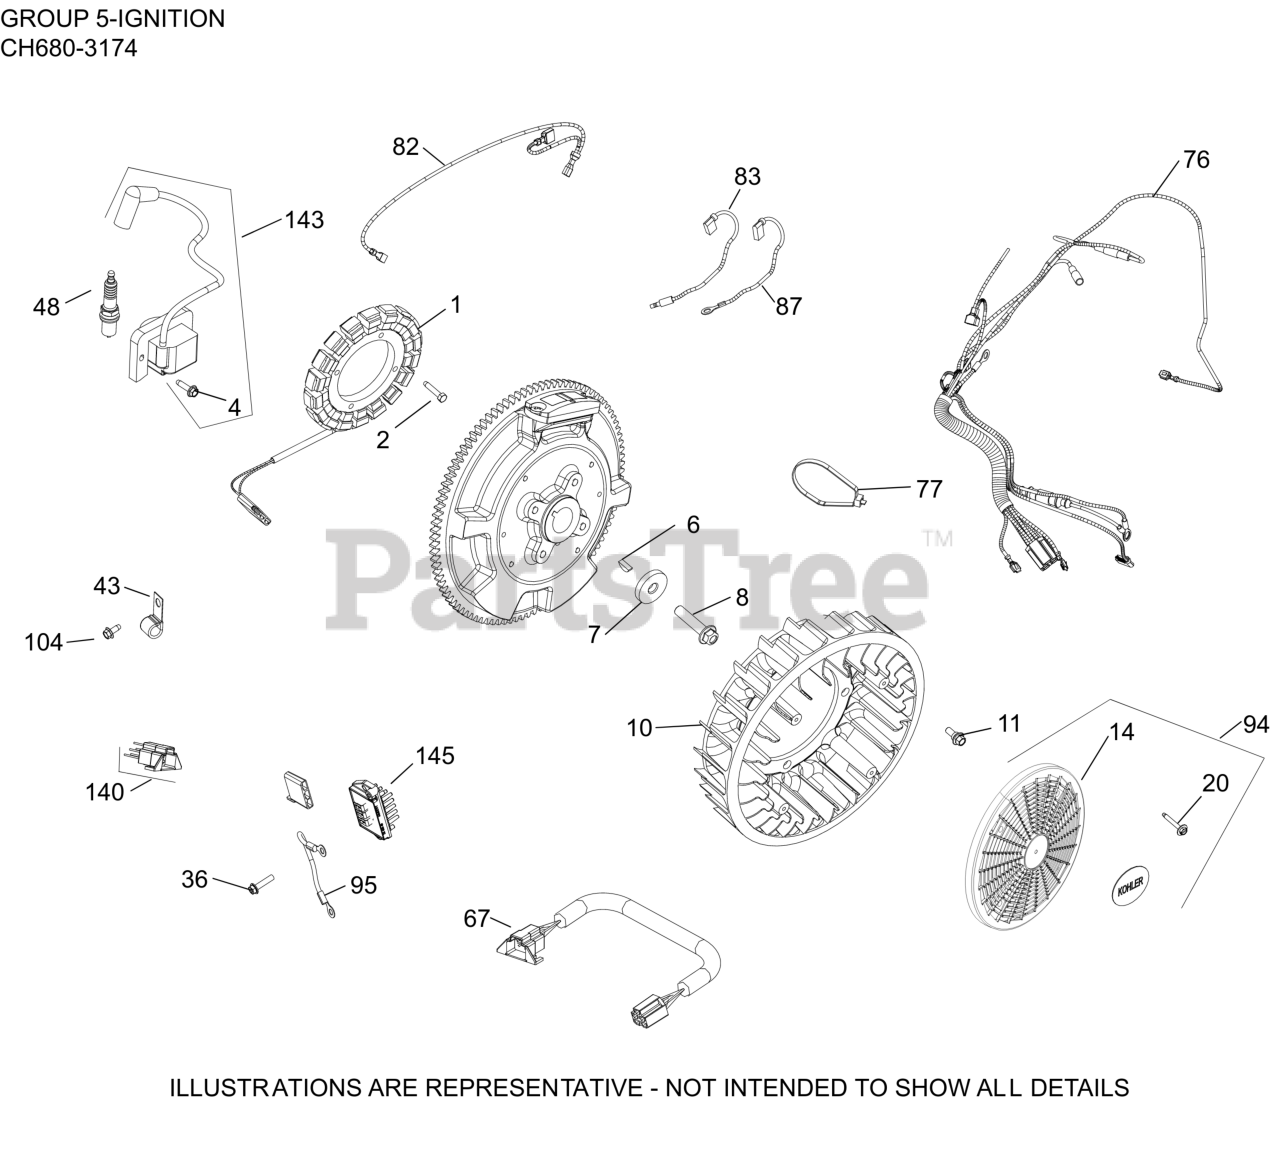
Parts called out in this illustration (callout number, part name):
1	KIT, 25 AMP STATOR ASSY.
2	SCREW, THREAD FORMING
4	SCREW, THREAD FORMING
6	KEY, 3/16" X 5/8"
7	WASHER, FLAT
8	SCREW, HEX FLANGE
10	FAN-USE 24 755 253-S
11	BOLT, SHOULDER
14	SCREEN, GRASS
20	SCREW, FLG SEMS M4x.7x25
36	SCREW, HEX FLANGE HI-LO
43	CLIP, CABLE
48	PLUG, SPARK (PRO SERIES)
67	CONNECTOR
76	HARNESS WIRING ASSEMBLY
82	LEAD, DUPLEX
83	LEAD, OIL SENTRY
87	LEAD, 20/25 AMP B+
94	KIT GRASS SCREEN
104	SCREW, THREAD FORMING
140	CONNECTOR
143	KIT IGNITION MODULE
145	REGULATOR, RECTIFIER (20-30AMP,FW W/OVP)
153	FLYWHEEL ASSEMBLY (LW, 22)
